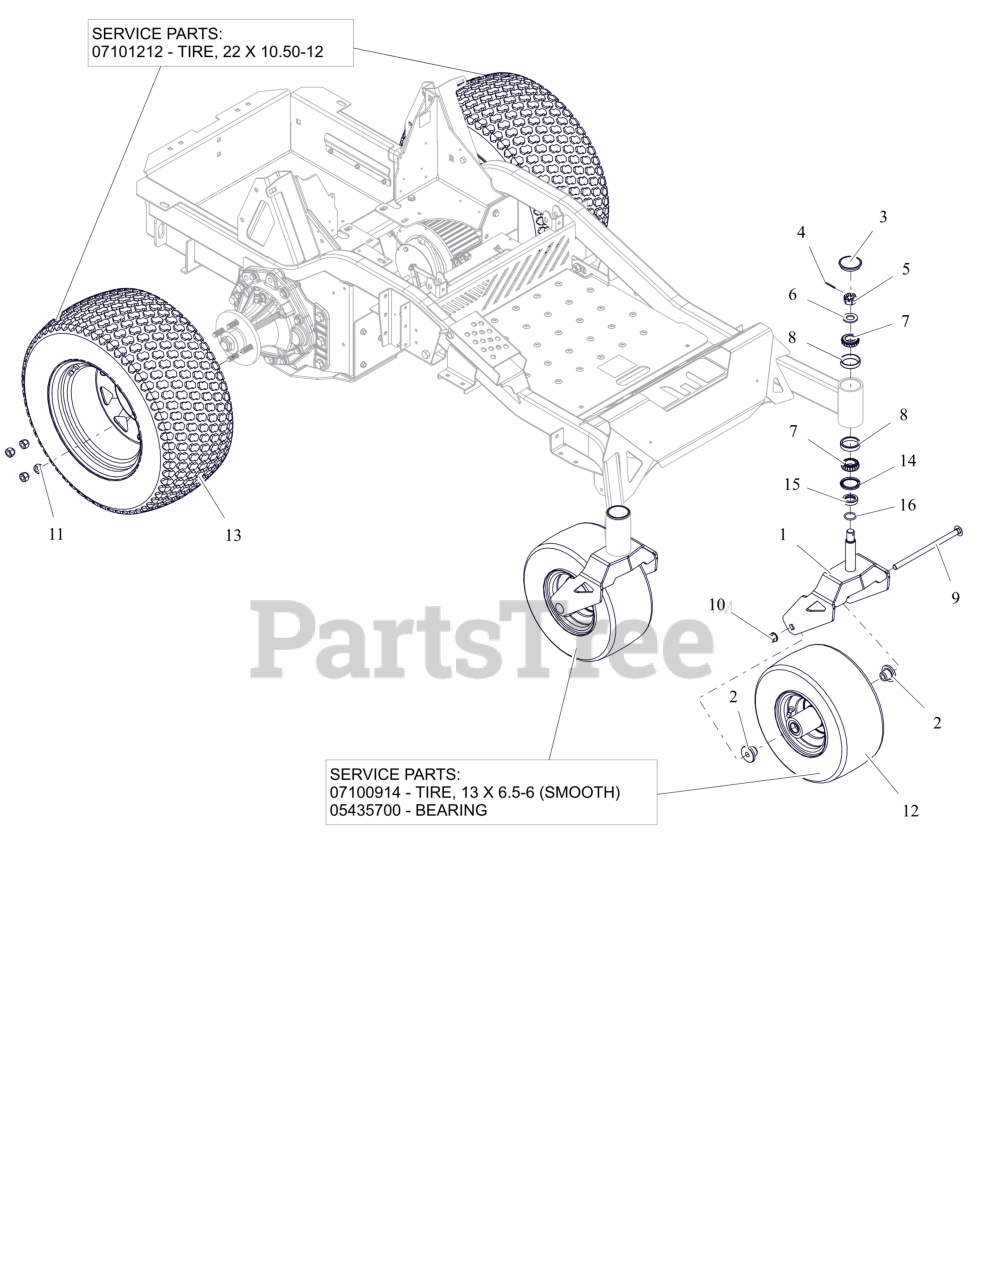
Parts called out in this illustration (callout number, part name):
1	WLDMT- CASTER FORK
2	SPACER, FRONT WHEEL
3	CAP, DUST
4	PIN,CTR.12X1.25EXTPRSQCT ZC120
5	NUT, SLOTTED .75-16
6	WSHR, FLT .812X1.469X.134 ZCC
7	BRG-CONE 1.0X.58
8	BRG-CUP1.980X.420
9	BLT, RHSN .50-13X9.00 G5 ZCC
10	NUT-LK-CTR-FLG .500-13 GG ZCC
11	NUT, WHEEL .50-20 ZCC
12	ASM, WHL/TIRE 13X6.50-6
12	LAWN TIRE FRONT, 13X6.50-6 SMOOTH
12	BRG, 25MM ID X 52MM OD X 15MM
12	TIRE TUBE, 13/6.5-6 4 PLY TR87 90 BENT VALVE
13	ASM, WHL/TIRE 22X10.50-12 K500
13	TIRE, 22X10.50-12
13	TIRE TUBE 22,23,24/8.50/9.50/10.00/10.50/12.00-12 4 PLY TR13 STRAIGHT VALVE
14	BEARING SEAL 1.5 X 2 X .18
15	SPCR, CASTER FORK (1.00)
16	O-RING 1.000X1.250X
